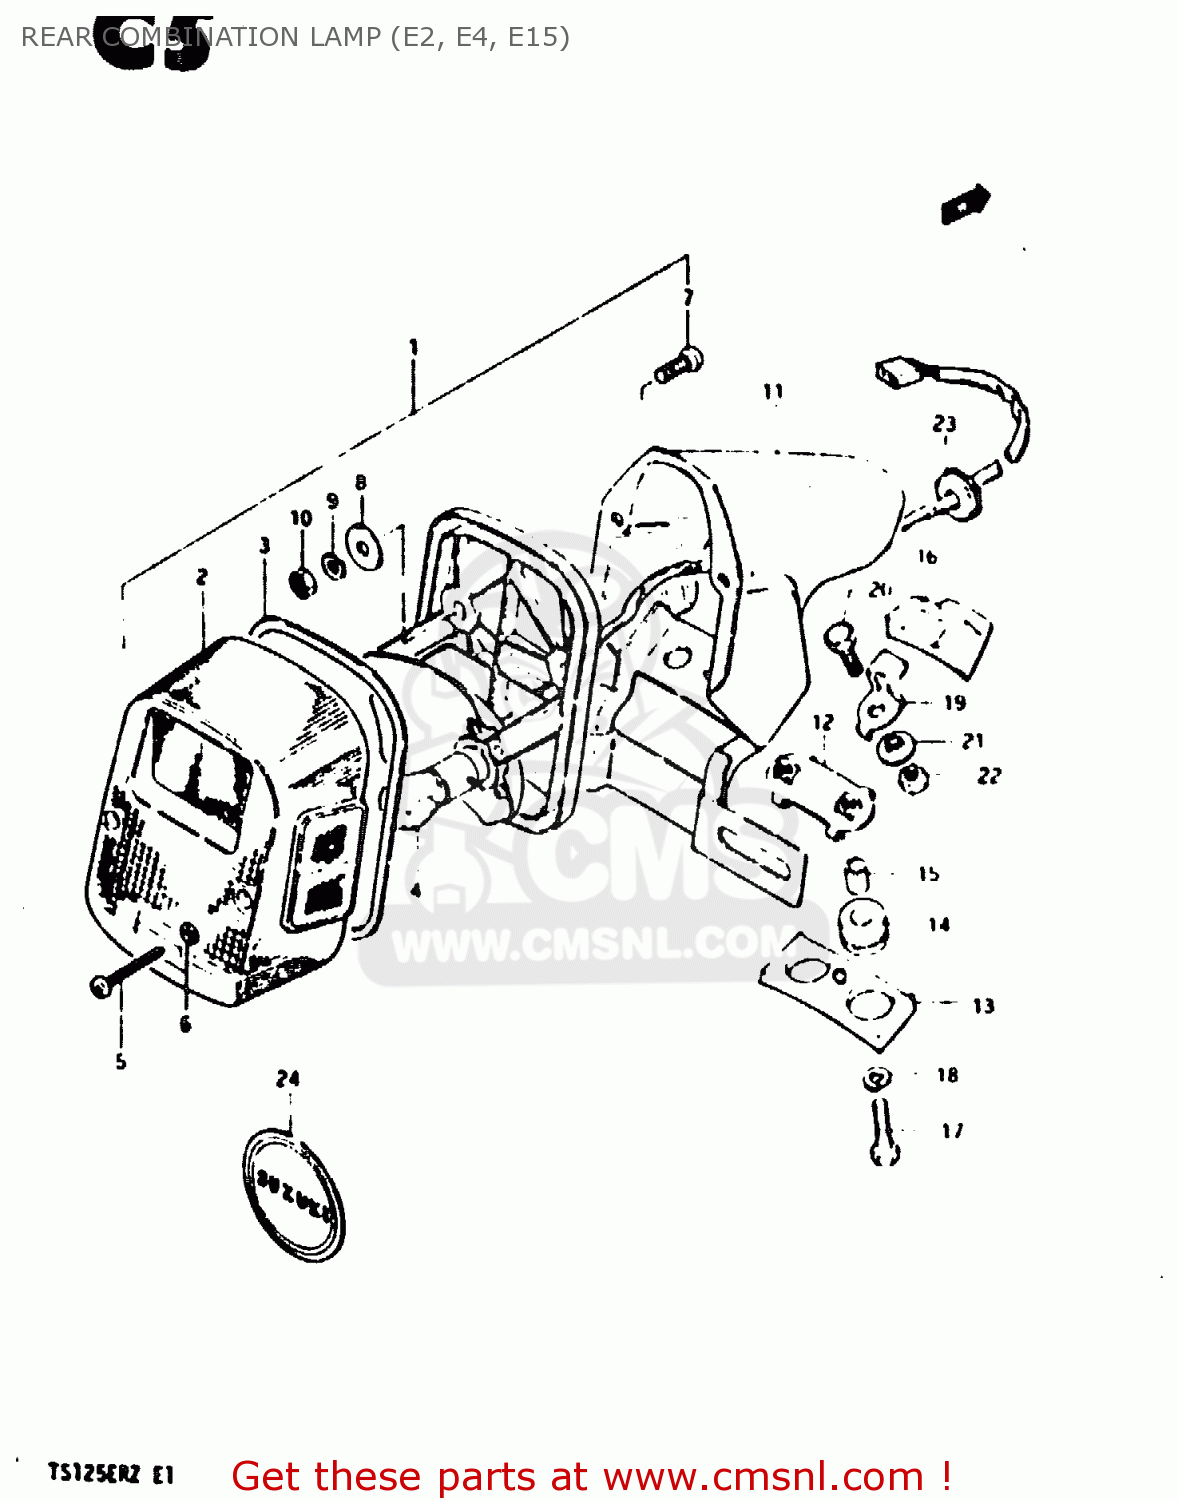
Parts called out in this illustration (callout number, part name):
1	LAMP UNIT, REAR COMBINATION
2	LENS
3	GASKET (NAS)
4	BULB 12V21/5W
5	SCREW TAPP.
6	GASKET (NAS)
7	SCREW
8	WASHER,REAR COMBINATION LAMP
9	LOCK WASHER
10	NUT
11	BRACKET UNIT,TAIL LAMP
12	PLATE
13	CUSHION
14	CUSHION
15	SPACER
16	CUSHION,REAR COMBINATION LAMP
17	BOLT
18	LOCK WASHER
19	PLATE,RR COMBINATION LAMP
20	BOLT, UPPER
21	WASHER,LOCK
22	NUT 6MM
23	GROMMET
24	EMBLEM, REAR
